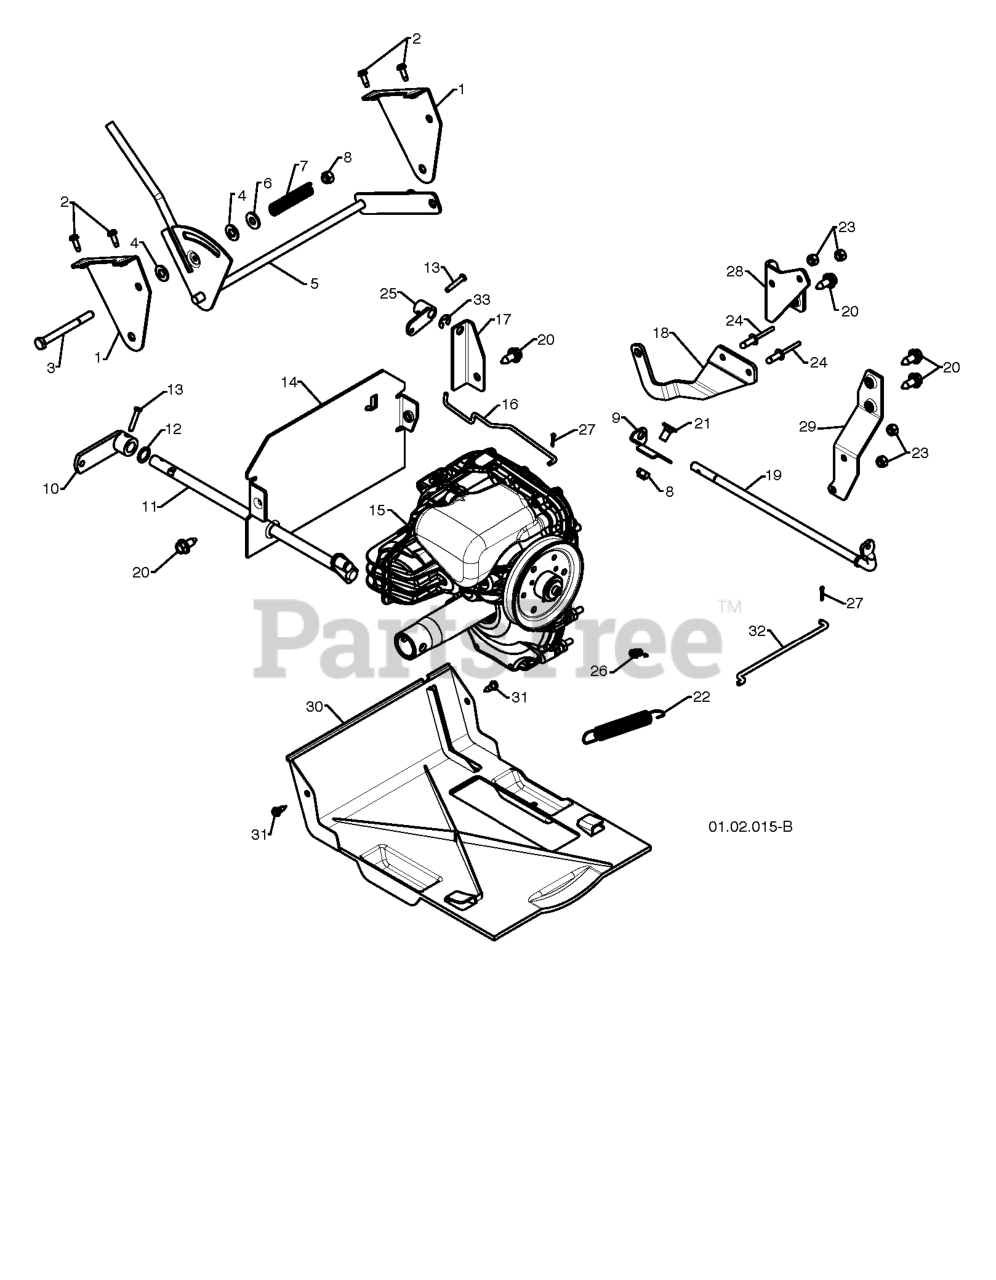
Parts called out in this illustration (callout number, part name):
1	BRACKET, SHIFT
2	SCREW #10-24 X 5/8
3	SCREW 5/16-18 X 3.25
4	WASHER, NYLON FRICTION
5	LEVER ASSEMBLY, SPEED CONTROL
6	WASHER.20X8.5
7	SRPING.FRICTION.HYDRO
8	NUT.71038.31-18.HEX.NYLOCK
9	FRONT CLUTCH BRACKET
10	ARM.CONTROL.AUGER
11	CONTROL.SHAFT.ASM
12	WASHER.FLAT.1/2
13	CLEVIS PIN
14	PLATE.REAR.HYDRO.ORANGE
15	TRANSMISSION.HYDRO.SNOW
16	ROD, BYPASS VALVE
17	REAR CLUTCH BRACKET
18	ARM.CONTROL.HYDRO.SNOW
19	SHAFT.HYD.CLUTCH
20	BOLT.HEX.HD.WASHER.5/16-18X.75
21	BOLT.CARRIAGE.5/16-18X
22	SPRING, BRAKE
23	LOCKNUT.NYLOC.1/4-20
24	RIVET.POP.1/4X.475
25	ARM.HYD.CLUTCH
26	SPRING, TRACTION IDLER
27	RETAINER CLIP
28	BRACKET, ANTI-ROTATE
29	STRAP.TORQUE.HYDRO
30	PAN.BOTTOM.PLASTIC
31	SCREW, HEX HEAD, TAPPING
32	RP ROD.HYD.CLUTCH
33	E-RING.RETAINER.REINFORCED.375
